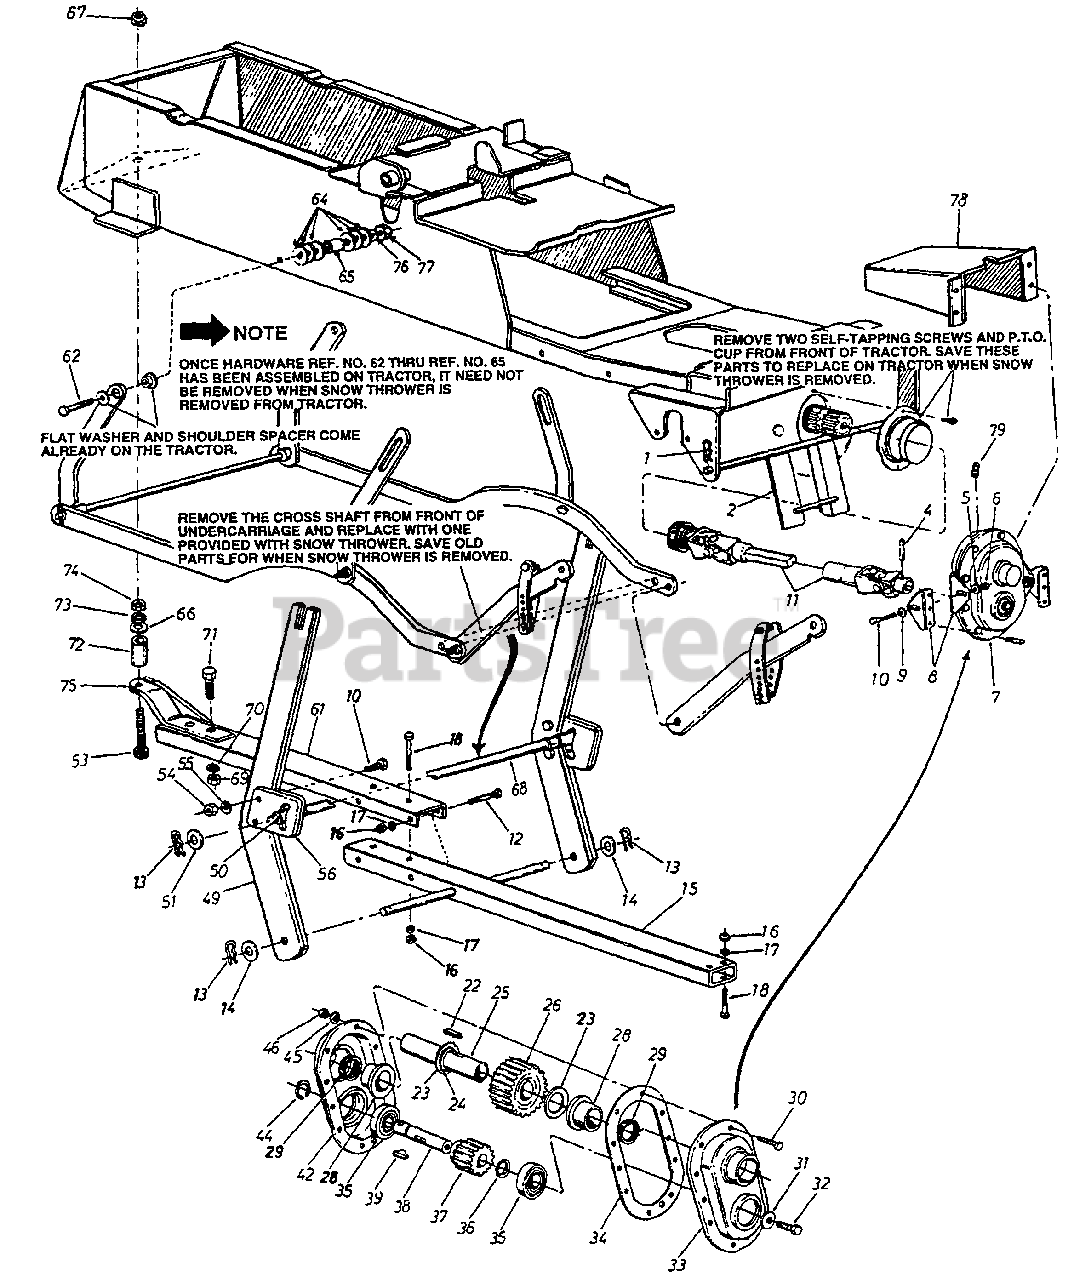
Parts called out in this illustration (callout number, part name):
1	intern. Cotter Pin 3/4" Dia.
2	Guide Bracket Ass'y.
4	Spring Pin Spiral 5/16" Dia. x 2.5" Lg.
5	Bell-Wash .341" I.D. x .88" O.D.
6	Hex Nut 5/16-18 Thd.
7	Gear Box Ass'y. Comp.
8	Gear Box Support Brkt.
9	Bell-Wash .341" I.D. x .88" O.D.
10	Hex Bolt 5/26-18 x .75" Lg.
11	Universal Drive Shaft Ass'y.
12	Hex Bolt 3/8-24 x 4.5" Lg.
13	Hairpin Cotter
14	Fl-Wash .62" I.D. x 1.12" O.D.
15	Lift Shaft Ass'y.
16	Hex Ins. Jam L-Nut 3/8-24 Thd.
17	L-Wash. 3/8" I.D.
18	Hex Bolt 3/8-24 x 2.75" Lg.
22	Fl-Wash. 1.31" I.D. x 2.0" 0.0. x .060
24	Snap Ring for 1/25" Dia. Shaft
25	Gear Shaft 1.25" Dia. x 6.0" Lg.
26	28 Teeth Spur Gear
28	Flange Brg. 1.25" I.D. x 1.75" O.D.
29	Oil Seal 1.25" i.D. x 1.75" O.D. x .26"
30	Hex Bolt 1/4-28 x .88" Lg.
31	Fl-Wash .40" I.D. x 1.25" O.D. x .160"
32	Hex L-Scr. 3/8-24 x 1.0" Lg.
33	Compl. Gear Hsg. Half - L.H.
34	Gasket
35	Ball Brg. 1.0" I.D. x 2.0" D.D.
36	Fl-Wash. 1.03" I.D. x 1.63" x .090"
37	15 Teeth Spur Gear
38	input Shaft
39	Woodruff Key 1/4" x 3/4" Dia.
42	Compl. Gear Hsg. Half - R.H.
44	Snap Ring for 1.0" Dia. Shaft
45	Spring Wash. 1/4" I.D.
46	Hex Nut 1/4-28 Thd.
51	Fl-Wash, .62" I.D. x 1.12" O.D.
53	Hex Bolt 5/8-18 x 4.0" Lg.
54	Hex Nut 5/16-18 Thd.
55	L-Wash. 5/16" I.D.
61	Lift Bracket
62	Hex Bolt 3/8-24 x 2.5" Lg.
64	Fl-Wash .375" I.D. x 1.0" O.D. x .135"
65	Spacer .275" I.D. x .625" O.D. x .440"
66	Fl-Wash. .62" I.D. x 1.12" O.D.
67	Hex Jam L-Nut 5/8-18 Thd.
68	Cross Shaft Ass'y.
69	Hex Nut 1/2-13 Thd.
70	L-Wash. 1/2" I.D.
71	Hex Bolt 1/2-13 x 1.25"
72	Bushing
73	L-Wash, 5/8" I.D.
74	Hex Jam Nut 5/8-18 Thd.
77	Hex Nut 3/8-24 Thd.
